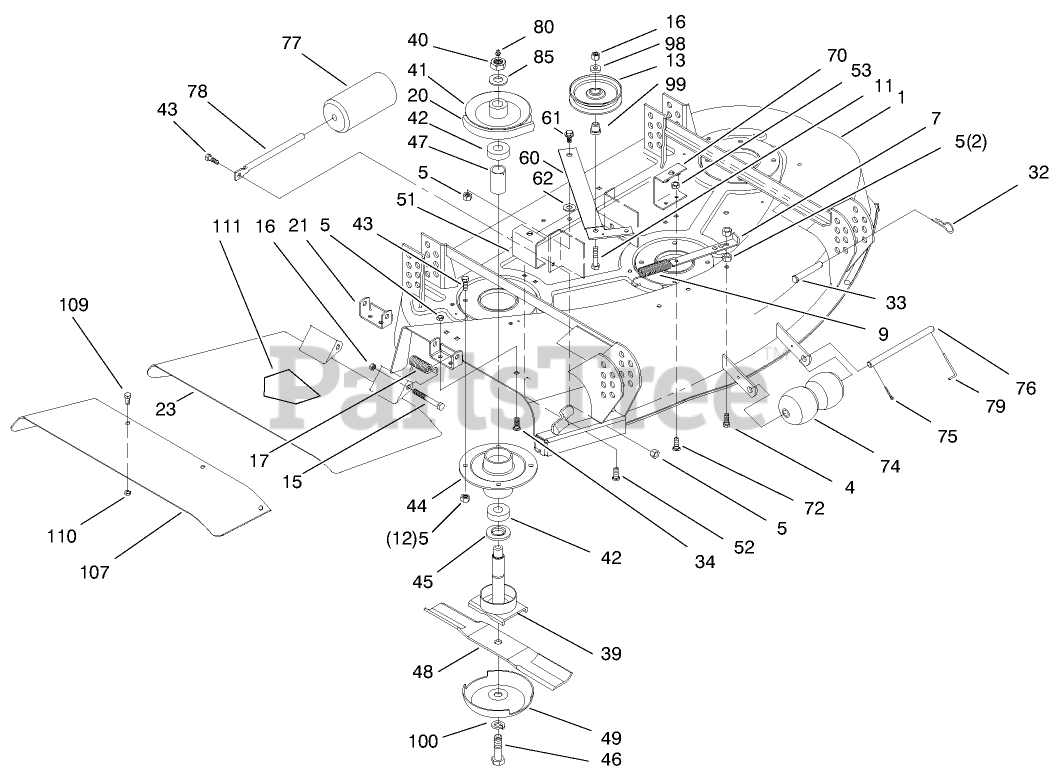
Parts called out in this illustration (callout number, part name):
4	SCREW-HH
5	NUT-LOCK, CONE
9	SPRING-EXTENSION, DECK
11	SCREW-HH
13	PULLEY-IDLER
15	SCREW-HH
16	NUT-HEX
17	SPRING
20	V-BELT-DECK
21	BRACKET-PIVOT
32	PIN-HAIR
33	PIN-CLEVIS
40	NUT-HEX
41	PULLEY-DECK
42	BEARING-BALL
43	SCREW-HH
44	HOUSING-SPINDLE
45	SPACER-SPINDLE
46	SCREW-BLADE
47	SPACER-BEARING
52	SCREW-CARR
53	NUT-LOCK, NI
61	SCREW-SHOULDER
62	WASHER
72	SCREW-CARR
74	ROLLER
75	PIN-COTTER
76	SHAFT-ROLLER
77	ROLLER-DECK
78	ROD-ROLLER
79	PIN-SPECIAL
80	FITTING-GREASE
85	WASHER
98	WASHER-FLAT
99	BUSHING-PULLEY
100	WASHER-LOCK
109	SCREW-HH
110	NUT-LOCK, NI
111	DECAL-DANGER
